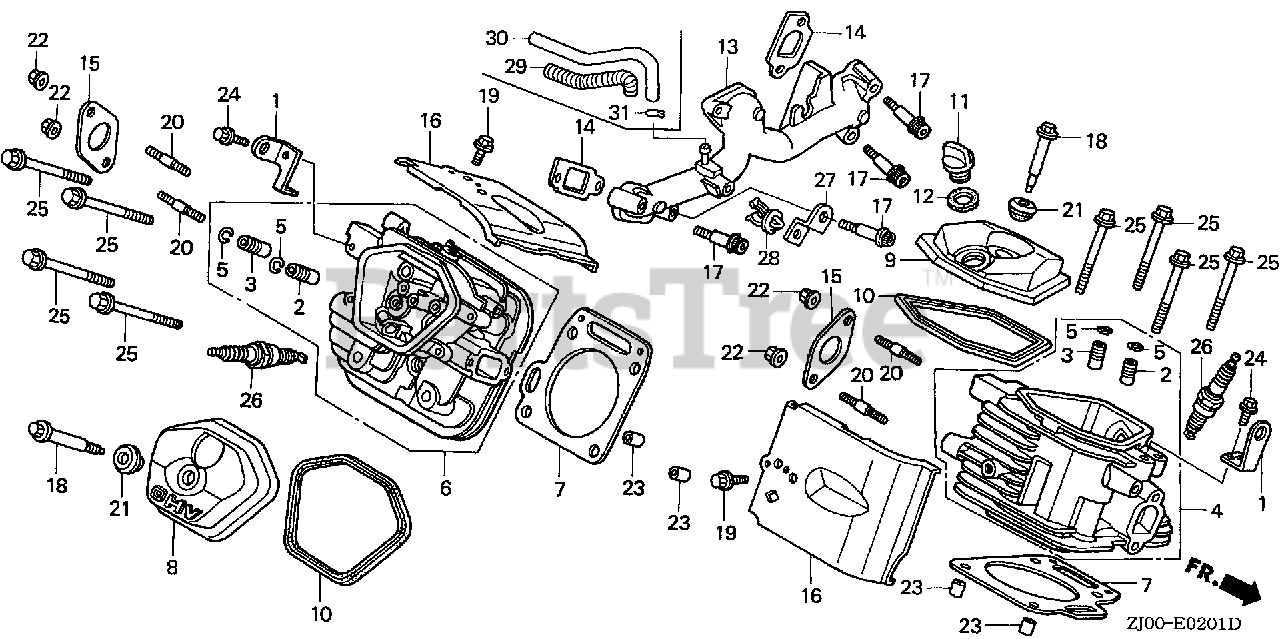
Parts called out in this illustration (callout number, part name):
1	HANGER, ENGINE
2	GUIDE, VALVE (OVER SIZE)
3	GUIDE, EX. VALVE (OVER SIZE)
4	CYLINDER HEAD (#1)
5	CLIP, VALVE GUIDE
6	CYLINDER HEAD (#2)
7	GASKET, CYLINDER HEAD
8	COVER, HEAD
9	COVER, HEAD FILLER
10	GASKET, HEAD COVER
11	CAP, OIL FILLER
12	GASKET, OIL FILLER CAP
13	MANIFOLD, IN.
14	GASKET, IN. MANIFOLD
15	GASKET, EX. PIPE
16	SHROUD, HEAD
17	BOLT, SOCKET (8X45)
18	BOLT, HEAD COVER
19	BOLT, FLANGE (6X14) (CT200)
20	BOLT, STUD (8X22)
21	WASHER, HEAD COVER
22	NUT, FLANGE (8MM)
23	PIN, DOWEL (12X20)
24	BOLT, FLANGE (8X20)
25	BOLT, FLANGE (10X80)
26	SPARK PLUG (BPR2ES) (NGK)
26	SPARK PLUG (J14CR-U) (DENSO)
26	SPARK PLUG (ZGR4A)
26	SPARK PLUG (J16CR-U) (DENSO)
26	SPARK PLUG (ZGR5A)
29	TUBE, CORRUGATE
30	BULK HOSE, FUEL (5.5X3000) (95001-550(95001-55001-60M)
31	CLAMP, TUBE (D10.5)
